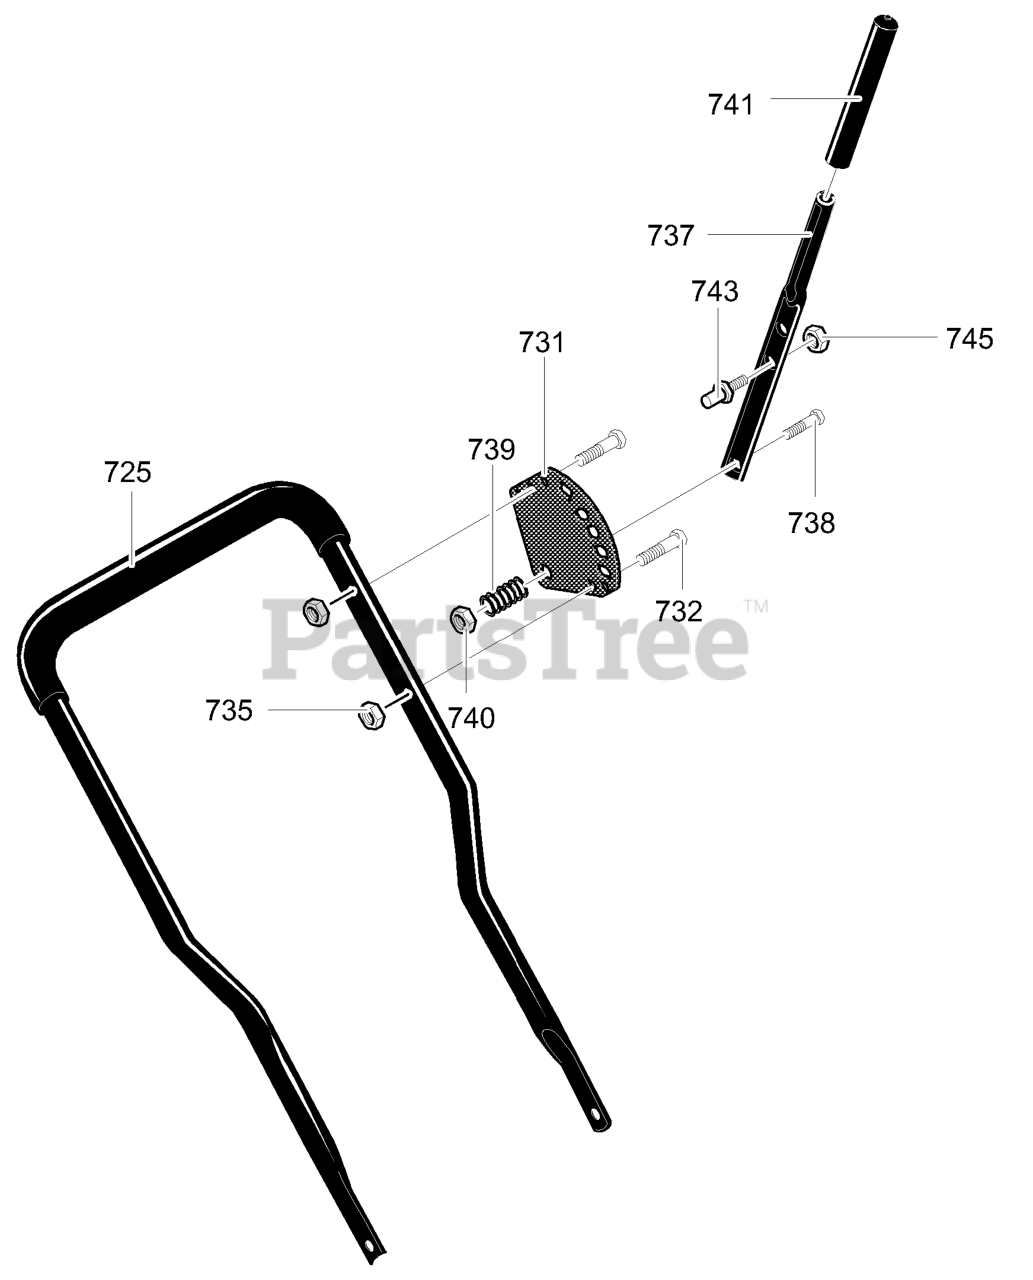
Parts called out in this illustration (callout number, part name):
725	Upper Handle & Foam
731	Selector Plate
732	Screw, 1/4-20x1.25
735	Nut, 1/4-20
737	Depth Adjust Handle
738	Screw, 5/16-18 x 1.25
739	Spring, Compression
740	Nut, 5/16-18
741	Grip, Hand
745	Nut, 3/8-16
